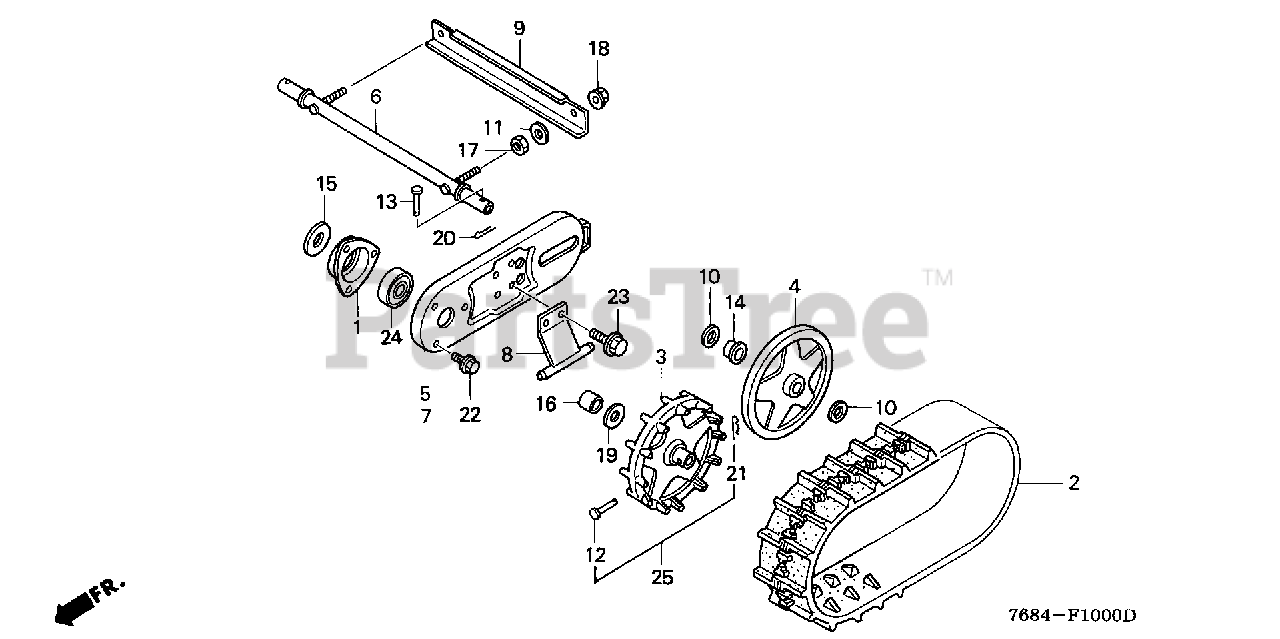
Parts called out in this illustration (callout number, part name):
1	HOLDER, WHEEL SHAFT BEARING
2	CRAWLER (12-60X21) (COO)
2	CRAWLER (12-60X21)
3	SPROCKET, CRAWLER
4	ROLLER, CRAWLER (COO)
5	PLATE, R. CRAWLER
6	PIPE, CRAWLER
7	PLATE, L. CRAWLER
8	GUIDE, CRAWLER
9	BAR, CRAWLER PLATE
10	WASHER, PLAIN (22MM)
11	WASHER, PLAIN (10MM)
14	COLLAR, CRAWLER PIPE
15	COLLAR, R. WHEEL SHAFT
16	COLLAR, CRAWLER SPROCKET
17	NUT, FLANGE (10MM)
18	NUT, FLANGE (10MM)
19	WASHER, PLAIN (20MM)
20	PIN, SPLIT (3.0X18)
21	PIN, SPLIT (3.0X18)
22	BOLT, FLANGE (6X12)
23	BOLT, FLANGE (8X14)
24	BEARING, RADIAL BALL (6004UU)
25	PIN SET, CRAWLER
